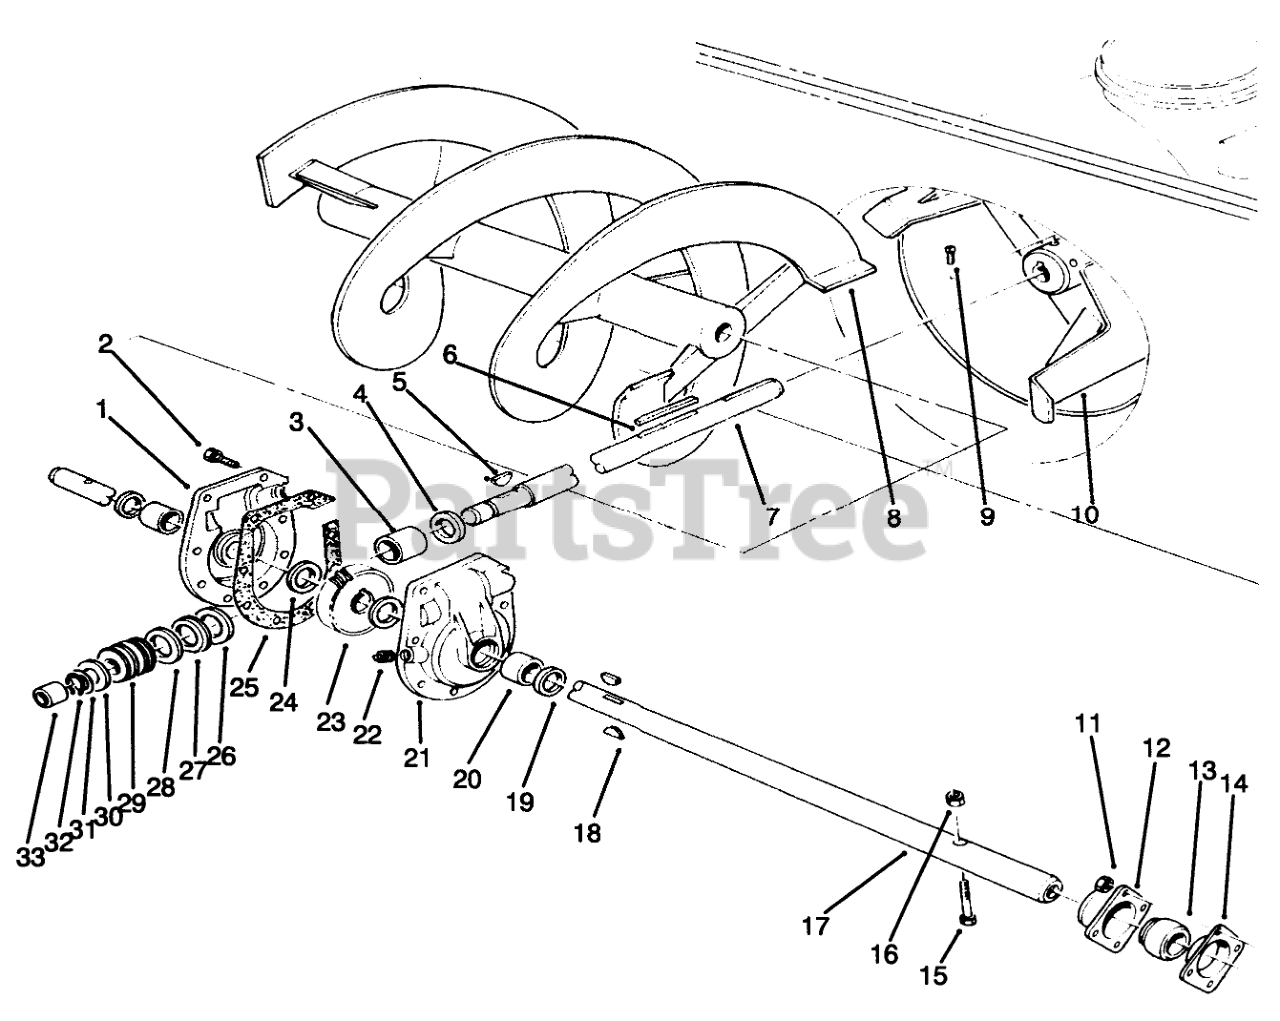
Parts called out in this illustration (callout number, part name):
1	Gear Case Assembly (Incl. Ref. #19 & 20)
2	SCREW-TAPTITE
3	BUSHING-SPECIAL
4	RING-QUAD
5	KEY-WOODRUFF
7	SHAFT-IMPELLER
8	Auger RH
9	SCREW-SET, SQH
10	IMPELLER ASM
11	NUT-LOCK, NI
12	BEARING-FLANGE, FRONT
13	BEARING
14	BEARING-FLANGE, REAR
15	SCREW-HH
16	NUT-LOCK, NI
17	SHAFT-AUGER
18	KEY-WOODRUFF
19	SEAL-OIL
20	BUSHING
21	Gear Case Assembly (Incl. Ref. #19 & 20)
22	PLUG-PIPE, SQH
23	GEAR-WORM, 27T
24	WASHER-THRUST
25	GASKET-CASE, GEAR
26	WASHER-THRUST
27	BEARING-THRUST
28	THRUST-WASHER
30	WASHER-THRUST
31	WASHER-SHIM
32	Ring-Snap
33	BUSHING
